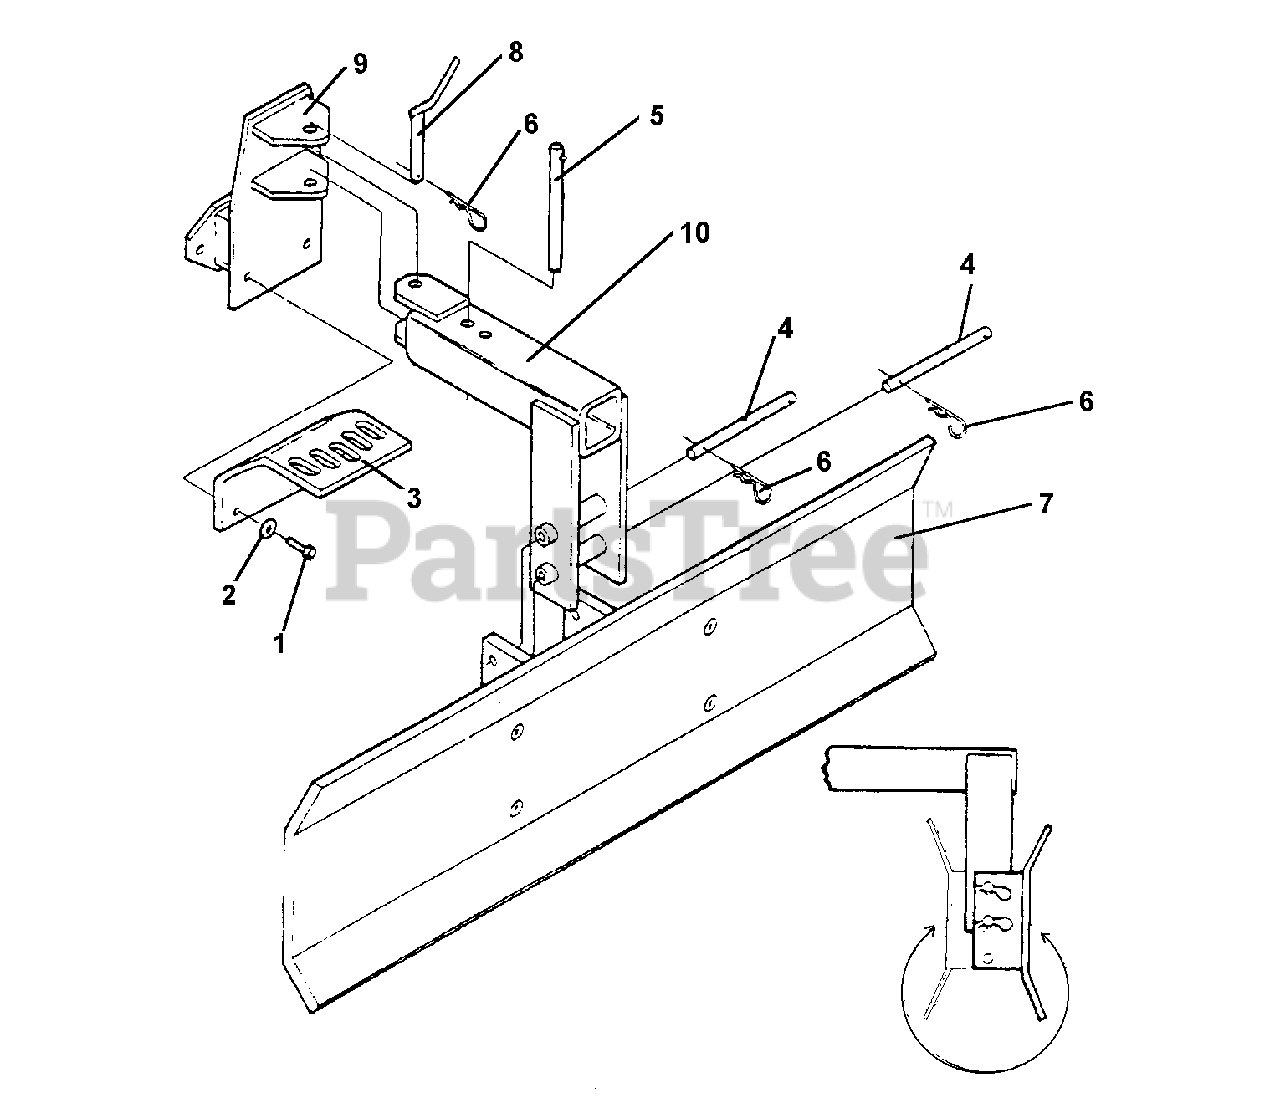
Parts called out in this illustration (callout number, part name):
2	FLAT WASHER
3	ANGLE BRACKET
5	PIN, ANGLE BRACKET
9	MOUNTING BRACKET
